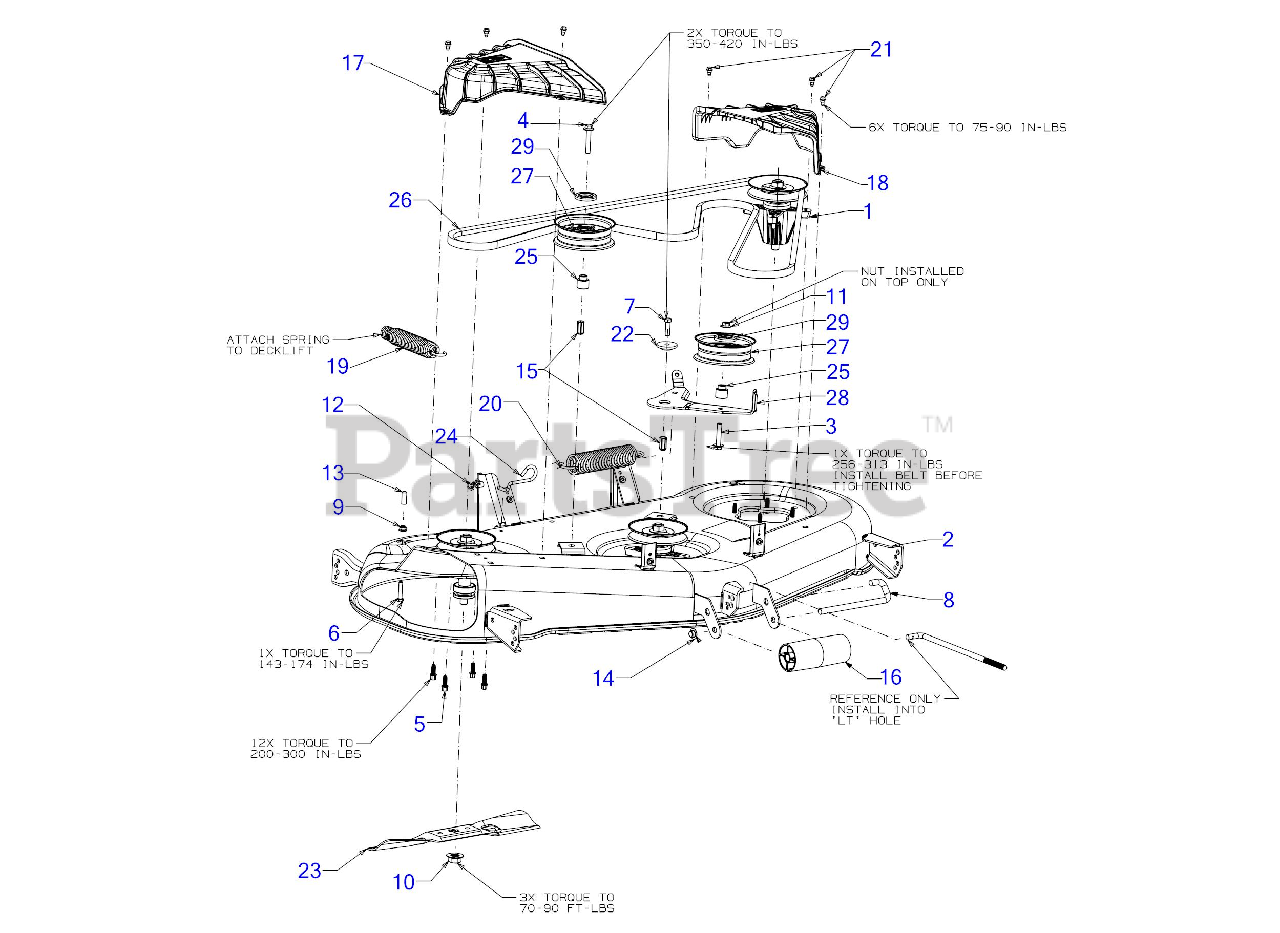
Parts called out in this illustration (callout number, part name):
1	SPINDLE ASSEMBLY
2	50" DECK SHELL
3	SCREW 3/8-16 x 2.0
4	SCREW 3/8-16 x 2.25 GR5
5	SCREW 5/16-18 X .875
6	SCREW 5/16-18 x 1.5 LG
7	SCREW 3/8-16 x 1.25 GR5
8	ROLLER PIN 1/2 x 7.31
9	FLANGE LOCK NUT 5/16-18
11	FLANGE LOCK NUT
12	BOW TIE COTTER PIN
15	NUT RIVET 3/8-16
17	SPINDLE COVER (RH)
18	SPINDLE COVER (LH)
19	LIFT ASSIST SPRING
20	EXTESION SPRING 1.75 OD X 8.5 LG
21	SHOULDER SCREW 1/4-20 x .50
22	SHOULDER SPACER
23	17.27" BLADE (2N1)
24	DECK SPRING HOOK
25	SHOULDER SPACER
26	V-BELT B SEC x 134
27	IDLER PULLEY 4.50" DIA
28	IDLER PIVOT BRACKET
29	IDLER PULLEY CAP
